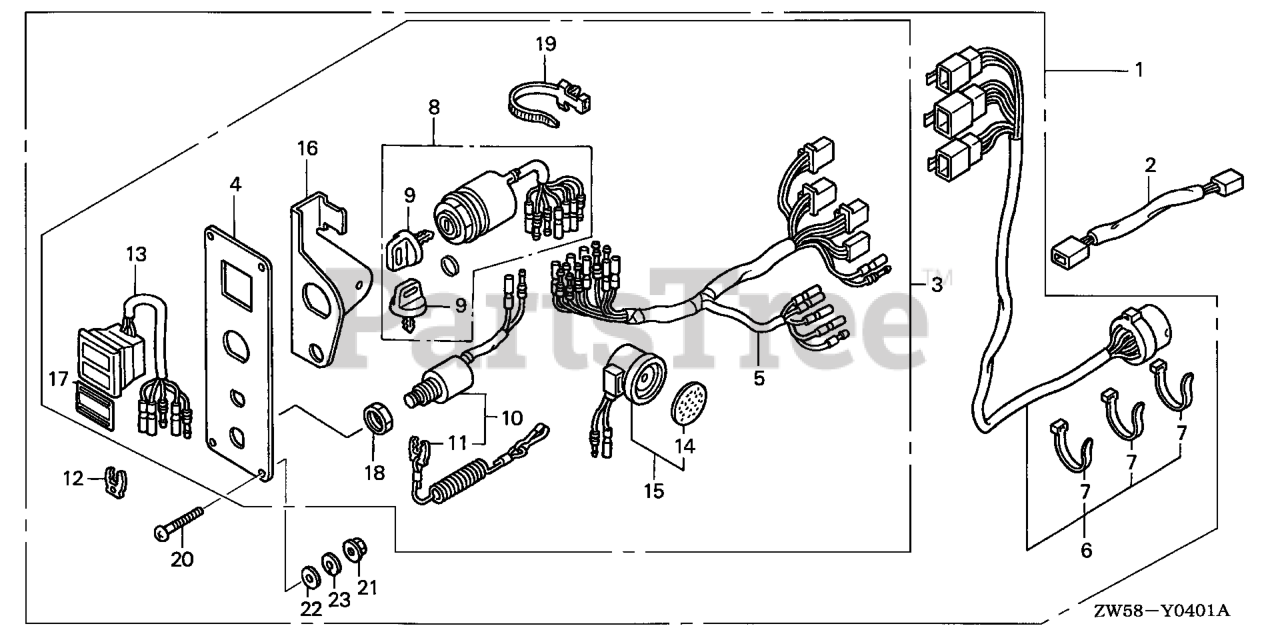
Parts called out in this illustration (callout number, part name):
1	PANEL KIT, SWITCH (SINGLE)
1	PANEL KIT, SWITCH (DUAL)
2	HARNESS ASSY., POWER TRIM-TILT Use from Frame SN 4000954.
3	PANEL ASSY., CONTROL (2-LED)
4	PANEL, CONTROL
5	HARNESS ASSY., SWITCH PANEL
6	CABLE ASSY., SWITCH PANEL
7	TIE, CABLE (NATURAL 2.4X92) Use up to Frame SN 1300359.
8	SWITCH ASSY., COMBINATION DUAL QTY = (2) (SINGLE)
9	KEY ASSY., COMBINATION SWITCH (35100-ZV5-003 ONLY) DUAL QTY = (4) (SINGLE)
10	SWITCH ASSY., EMERGENCY STOP
11	WIRE, EMERGENCY (SINGLE) (DUAL)
12	CLIP, EMERGENCY LOCK
13	LAMP ASSY., INDICATION (2-LED) DUAL QTY = (2) (SINGLE)
14	PLATE, TURN SIGNAL BUZZER DUAL QTY = (2) (SINGLE)
15	BUZZER, WARNING DUAL QTY = (2) (SINGLE)
16	BRACKET, BUZZER DUAL QTY = (2) (SINGLE)
17	MARK, SWITCH PANEL DUAL QTY = (2) (SINGLE)
18	NUT, HEX. (16MM) DUAL QTY = (2) (SINGLE)
19	BAND, WIRE HARNESS (150MM) (NATURAL) DUAL QTY = (2) (SINGLE)
20	SCREW, PAN (5X40) DUAL QTY = (8) (SINGLE)
21	NUT, FLANGE (5MM) DUAL QTY = (8) (SINGLE)
22	WASHER, PLAIN (5MM) DUAL QTY = (8) (SINGLE)
23	WASHER, SPRING (5MM) DUAL QTY = (8) (SINGLE)
